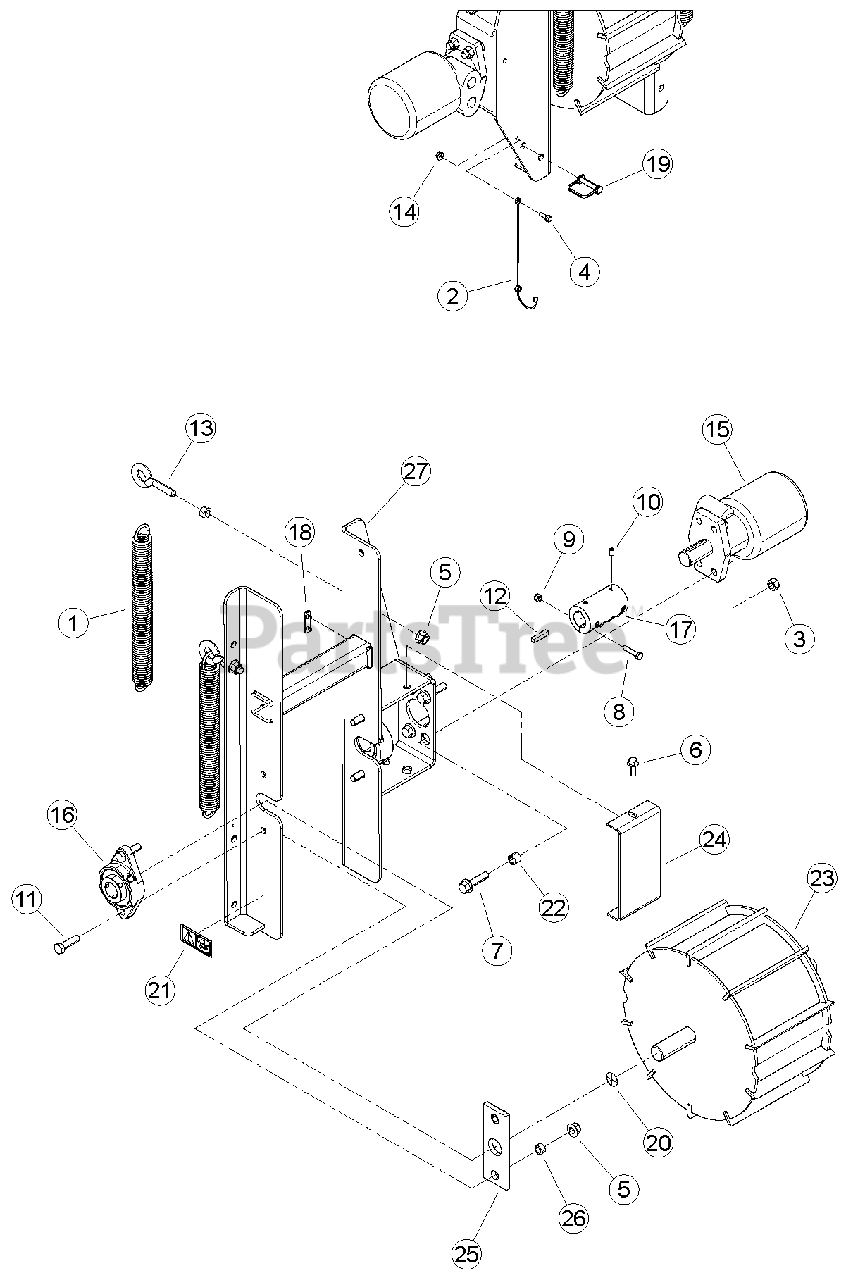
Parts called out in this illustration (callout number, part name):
1	SPRING, EXTENSION
2	LANYARD, NYLON
3	NUT, 1/2" CENTERLOCK GRB ZP
4	BOLT, 1/4-20 X 3/4 HWH GR5 CZP
5	NUT, 1/2-13 NYLOCK FLANGE
6	BOLT, 3/8 X 1 FLANGE NC
7	BOLT, 1/2-13 X 2 HWH GR5 CZP
8	BOLT, 5/16 X 1-1/2 GR5 HEX CPS ZP
9	NUT, 5/16" NE NYLOCK ZP
10	SET SCREW, 3/8 X 1/2 CUP PT SKT
11	BOLT, 1/2 X 1 3/4 GR5 HCPS NC ZP
12	KEY, 5/16 X 1-1/2 SQUARE
13	EYEBOLT, 1/2 X 2" ZP
14	NUT, 1/4-20 NYLOCK-FLANGE
15	MOTOR, 45 CU IN HYDRAULIC
16	BEARING, 1-1/4" DIA 2 BOLT FLANGE
17	COUPLER, 1-1/4 SHAFT
18	WEAR PAD, STD. SPRING HD FRONT
19	PIN, SNAP 3/8 X 1-1/2 USABLE LGH
20	DECAL, ROTATING SHAFT
21	DECAL, CRUSHING ISO
22	SPACER, 0.75 X 0.620
23	WELDMENT, TOP GRAB ROLLER
24	SHIELD, COUPLER
25	BEARING, SLIDE
26	SPACER, .75 OD X .5 ID X .37
27	WELDMENT, ROLLER SLIDE
